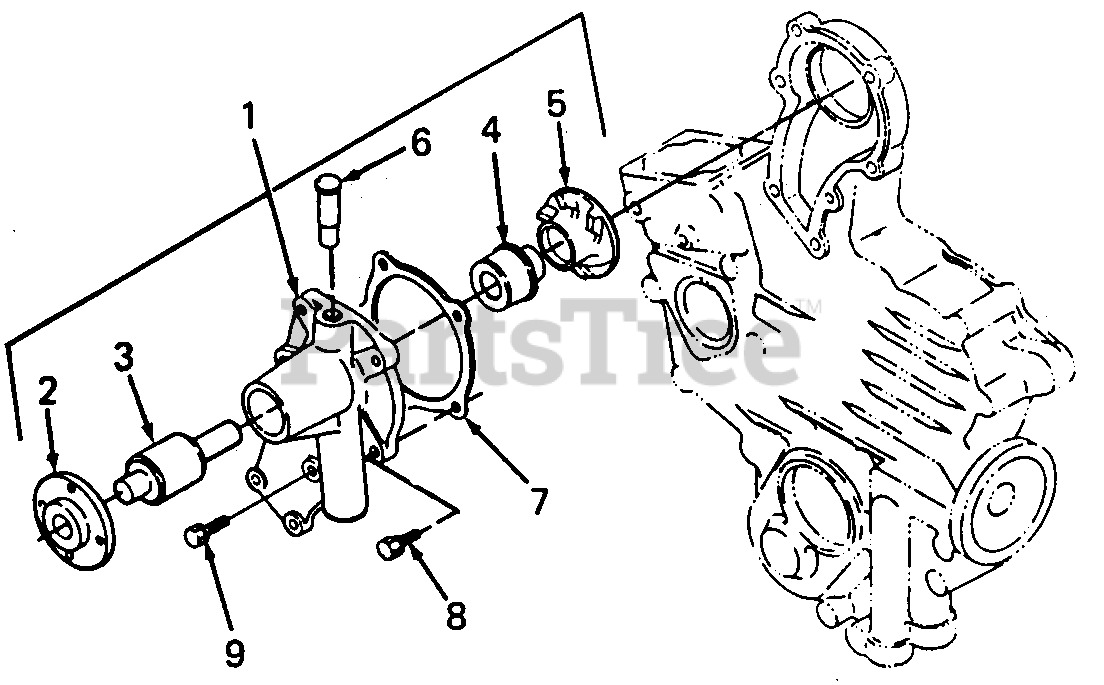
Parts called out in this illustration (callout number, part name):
1	Water Pump Assy
2	Flange, Water Pump
3	Bearing, Ball
4	Mechanical Seal Assy
5	Impeller, Water Pump
6	Pipe, Water Return
7	Gasket, Water Pump
